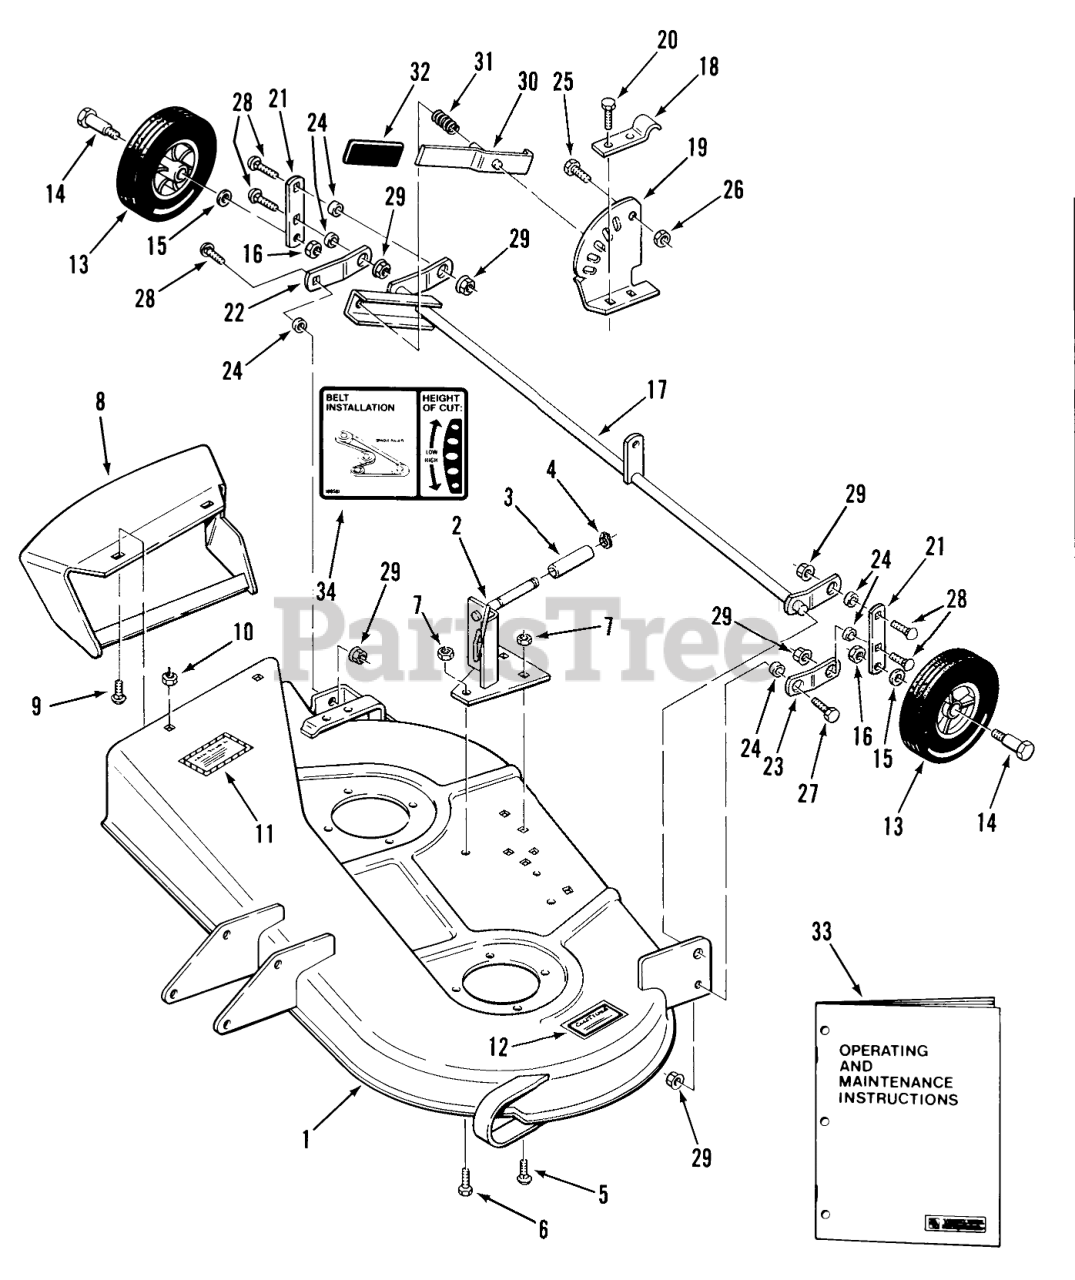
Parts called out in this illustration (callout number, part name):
1	Mower Deck
2	Rear Hanger Support
3	SPACER
4	Snap Ring
5	CARRIAGE BOLT -9
6	Bolt
7	Nut
8	ASSY-CHUTE EXT R
9	CARRIAGE BOLT -4
10	Nut
11	DECAL
12	Caution Decal
13	WHEEL-GAUGE
14	BOLT
15	WASHER
16	Nut
17	Gage Wheel Support
18	Pivot Bracket
19	Quadrant
20	Bolt
21	LINK R
22	ARM-PIVOT RH R
23	Arm LH
24	SPACER
25	HHCS
26	Nut
27	BOLT
28	Bolt
29	LOCKNUT-FLANGE
30	Lever
31	SPRING-COMPRESSION
32	GRIP
33	Operating and Maintenance Instructions
34	DECAL-BELT&HEIGHT
